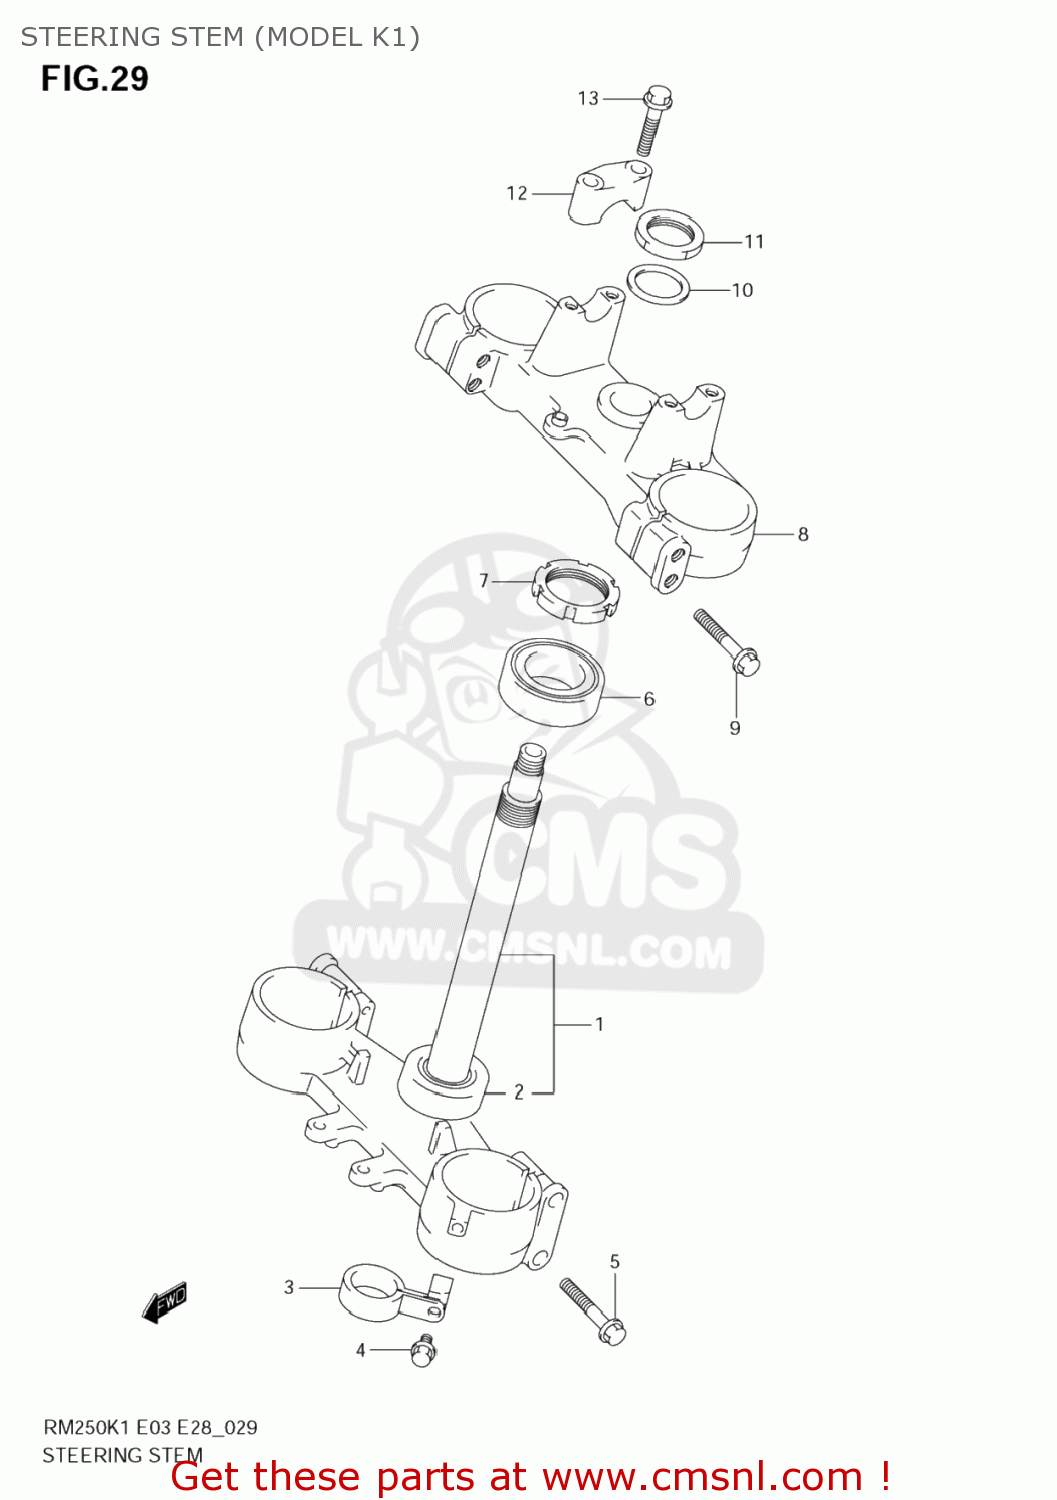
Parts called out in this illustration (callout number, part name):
1	STEM,STEERING
2	BEARING(30X52X16)
3	GUIDE,FR BRAKE HOSE
4	BOLT
5	BOLT
6	BEARING(30X52X16)
7	NUT,STEERING
8	HEAD,STEERING STEM
9	BOLT
10	WASHER,STEM HEAD(24.5X34X1.6)
11	NUT
12	HOLDER,HANDLE
13	BOLT
